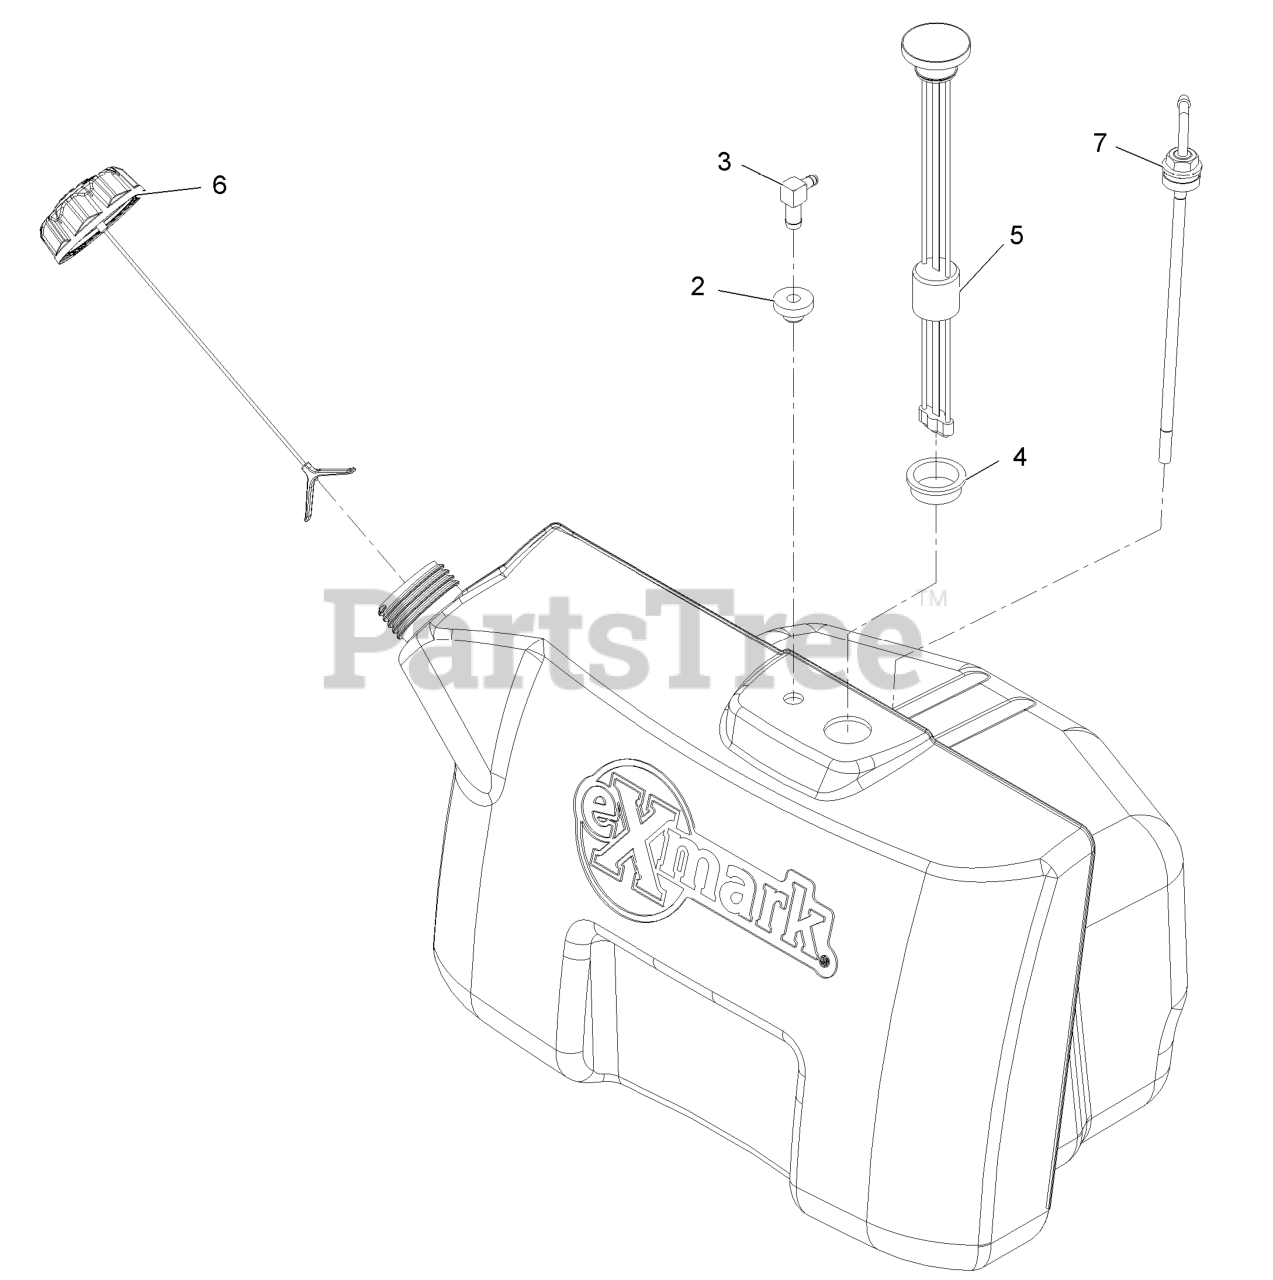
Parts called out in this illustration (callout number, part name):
2	BUSHING
3	ELBOW-90 DEG
4	CONTACT ORDER SERVICES
7	FITTING-FUEL, BULKHEAD
